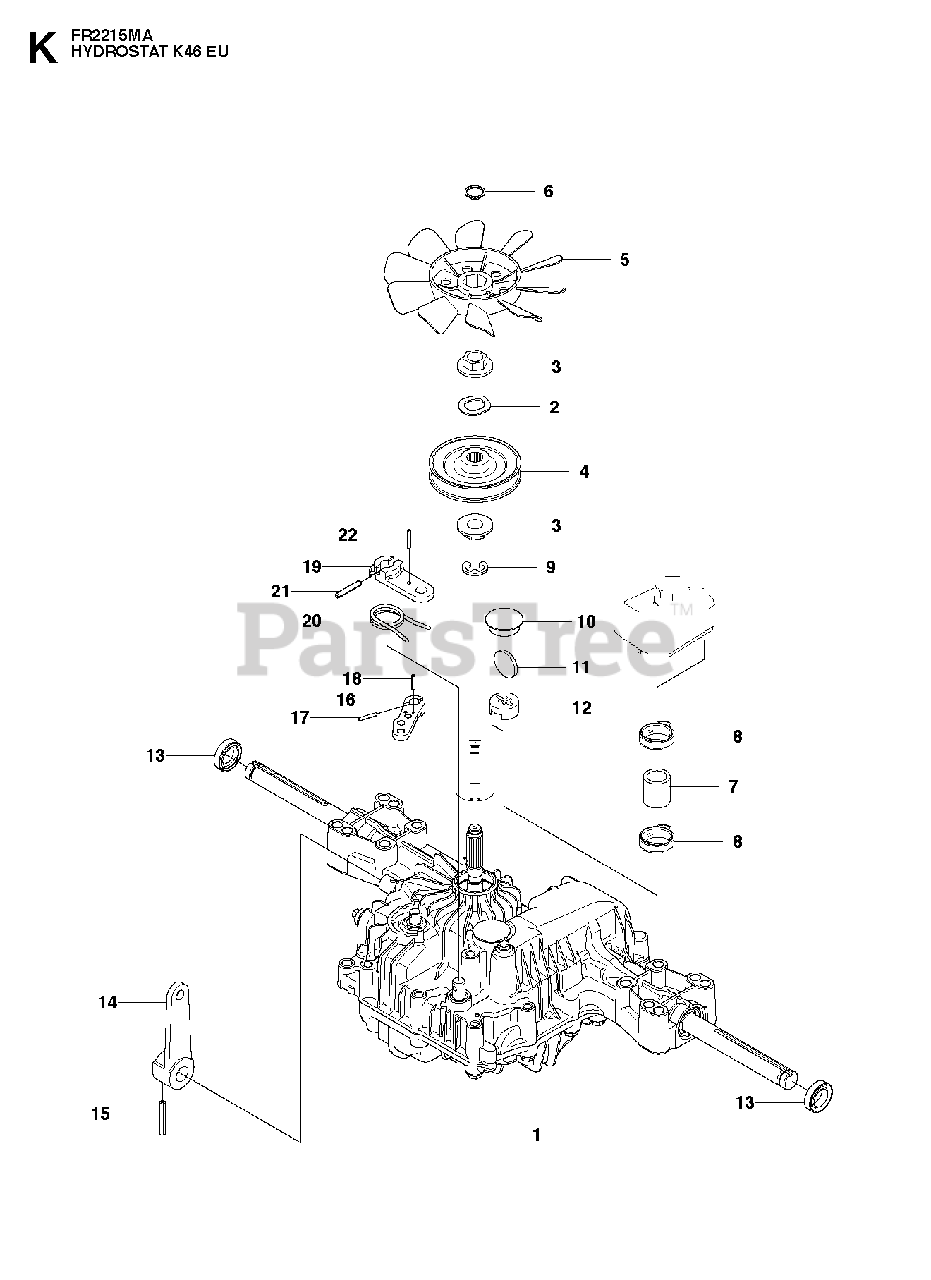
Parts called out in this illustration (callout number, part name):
1	HYDROSTAT
2	WASHER **
5	FAN
6	RETAINING RING **
8	CLAMP
9	CLIP
10	PLUG
11	MAGNET
12	MAGNET HOLDER
13	SEALING
14	CONTROL LEVER
15	PIN
16	ARM
17	PIN
18	PIN
19	ARM
20	RETURN SPRING
21	PIN
22	PIN
